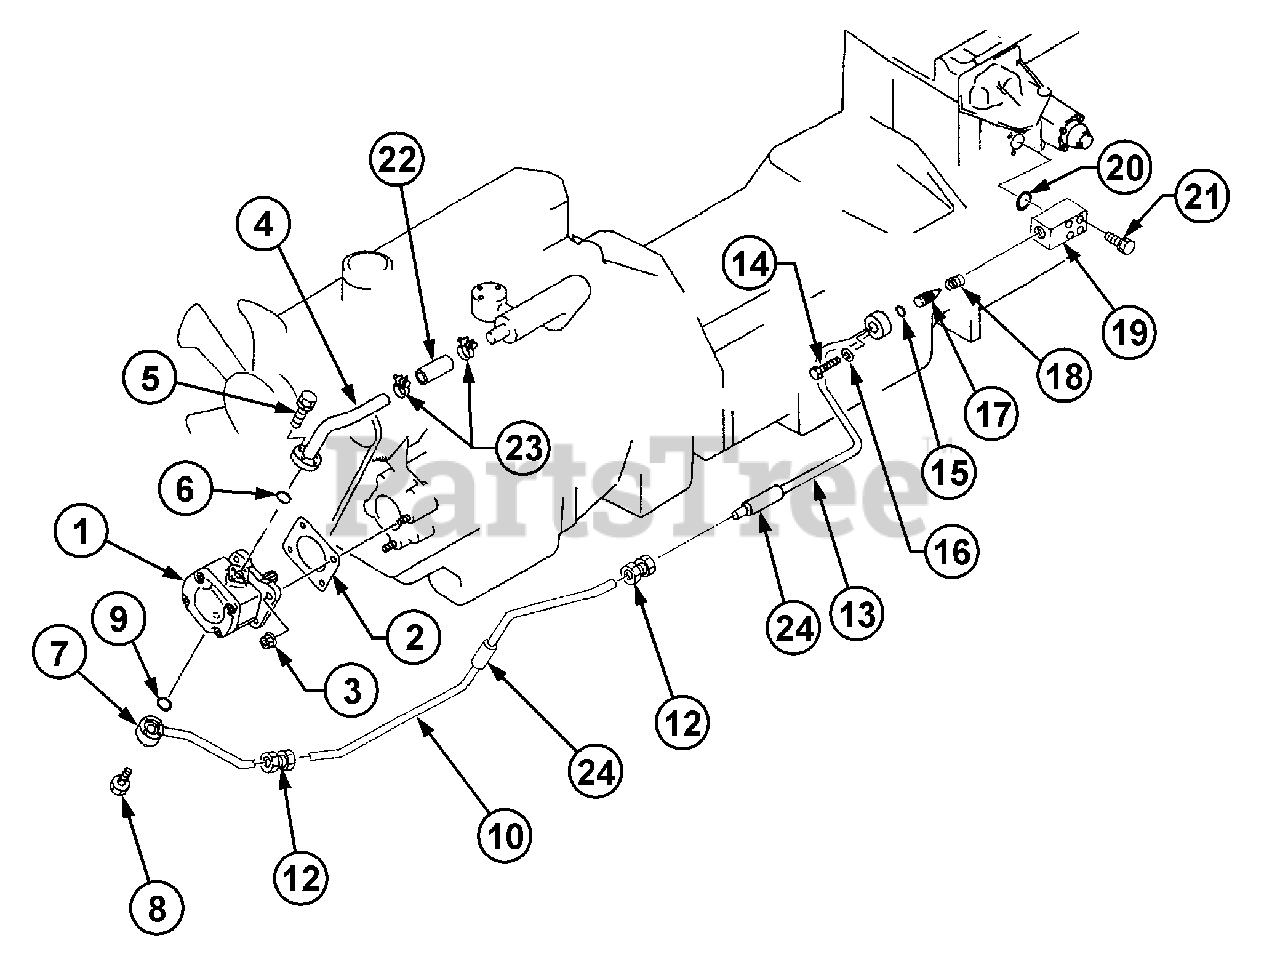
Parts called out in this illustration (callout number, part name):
4	Pipe Suction P
8	Bolt, w/Washer
13	Pipe P/S B Assy
21	Bolt, w/Washer
